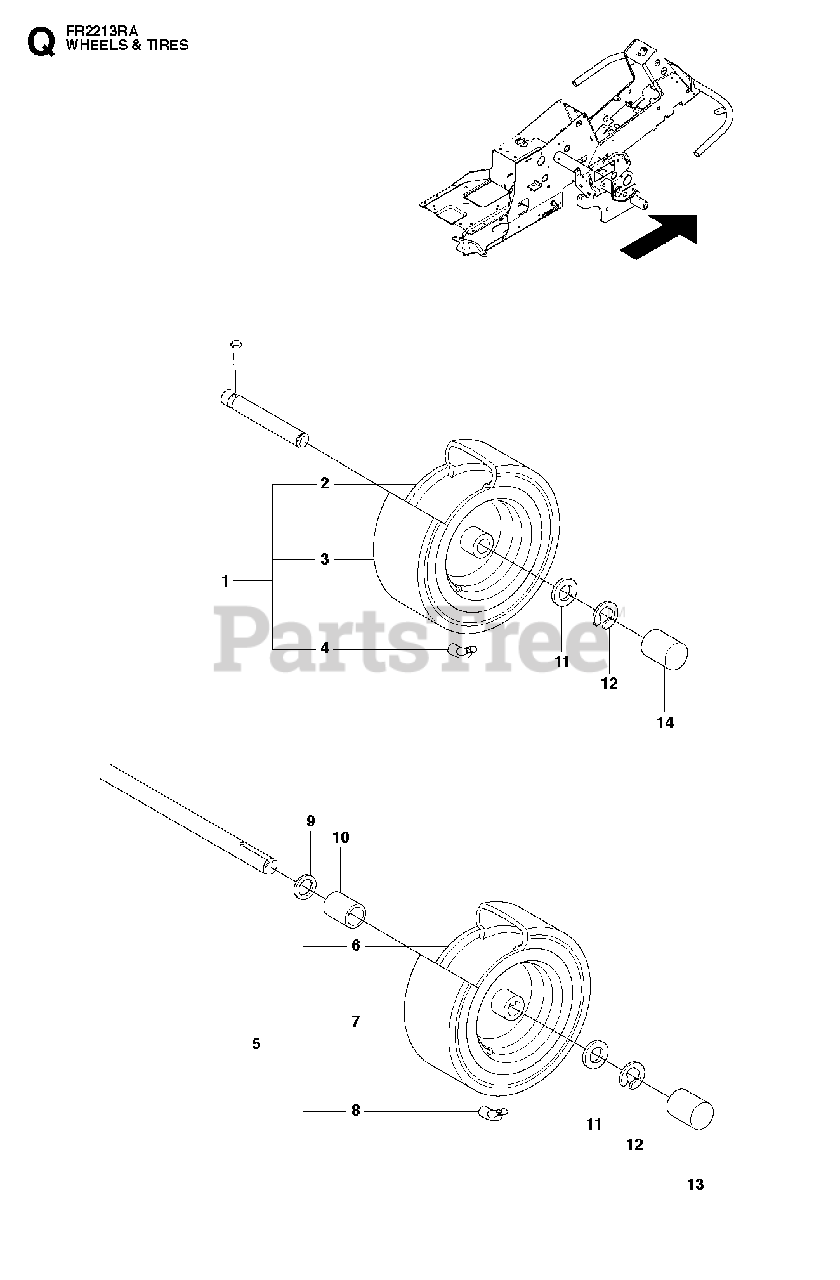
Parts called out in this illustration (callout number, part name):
10	SPACE SLEEVE
12	RETAINING RING
13	DUST CAP
